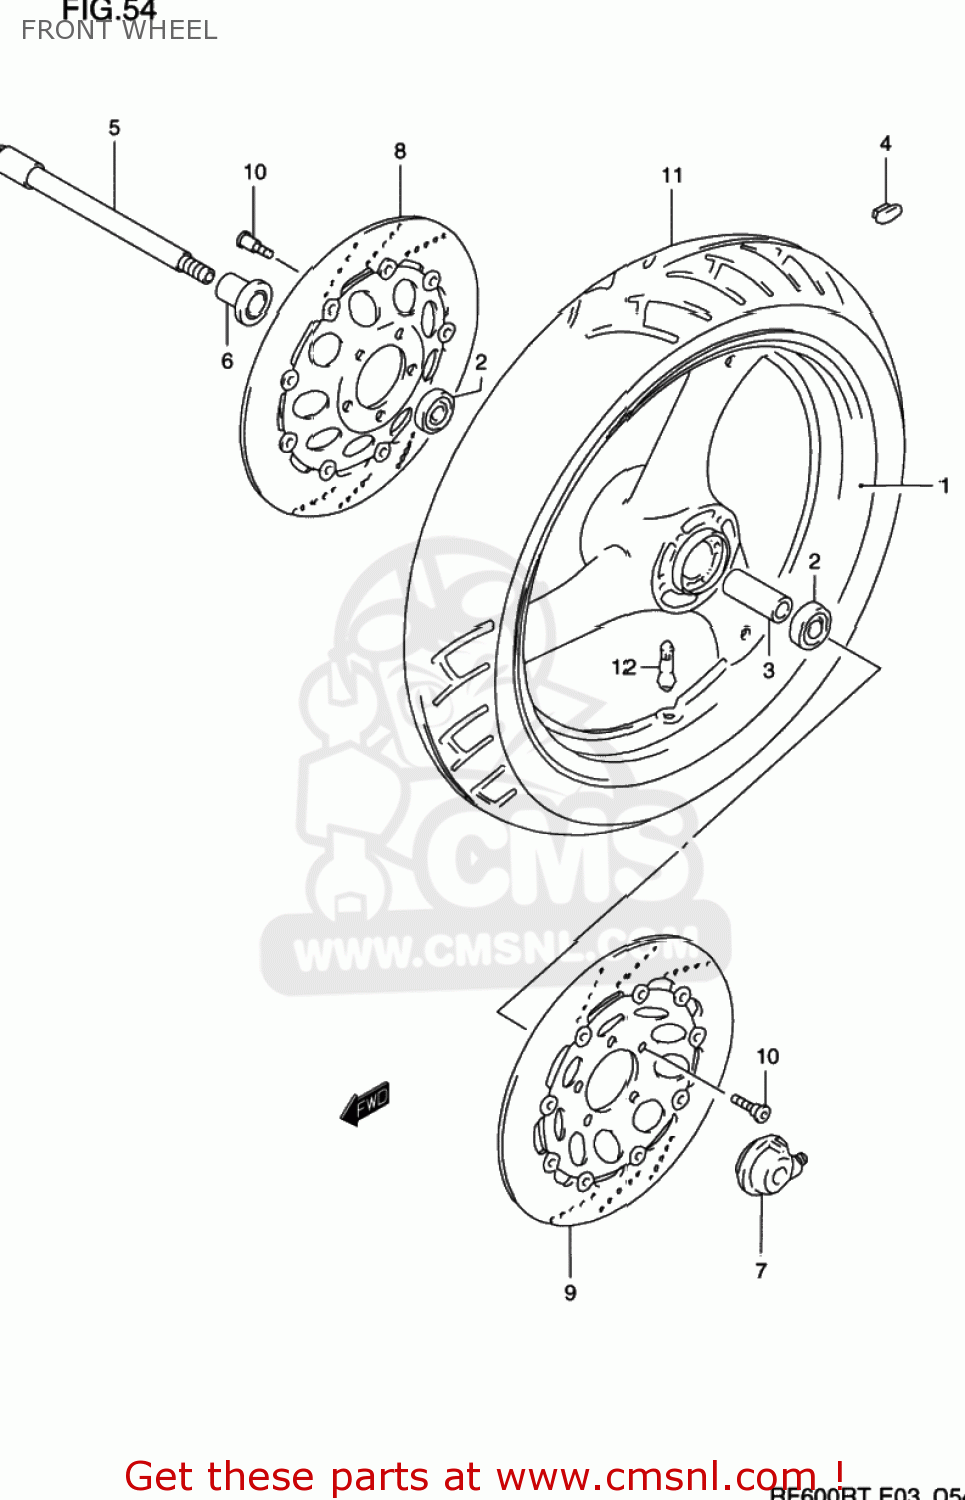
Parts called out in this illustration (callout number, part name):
1	WHEEL,FRONT
2	BEARING
3	SPACER(17.5X22.5X73)
4	BALANCER,WHEEL
5	AXLE,FR
6	SPACER,FR AXLE,R
7	BOX ASSY,SPEEDOMETER GEAR
8	DISC,FR BRAKE,R
9	DISC,FR BRAKE,L
10	BOLT 8X33
11	TIRE,FRONT 120/70 ZR17
12	VALVE ASSEMBLY,WHEEL,TR412
